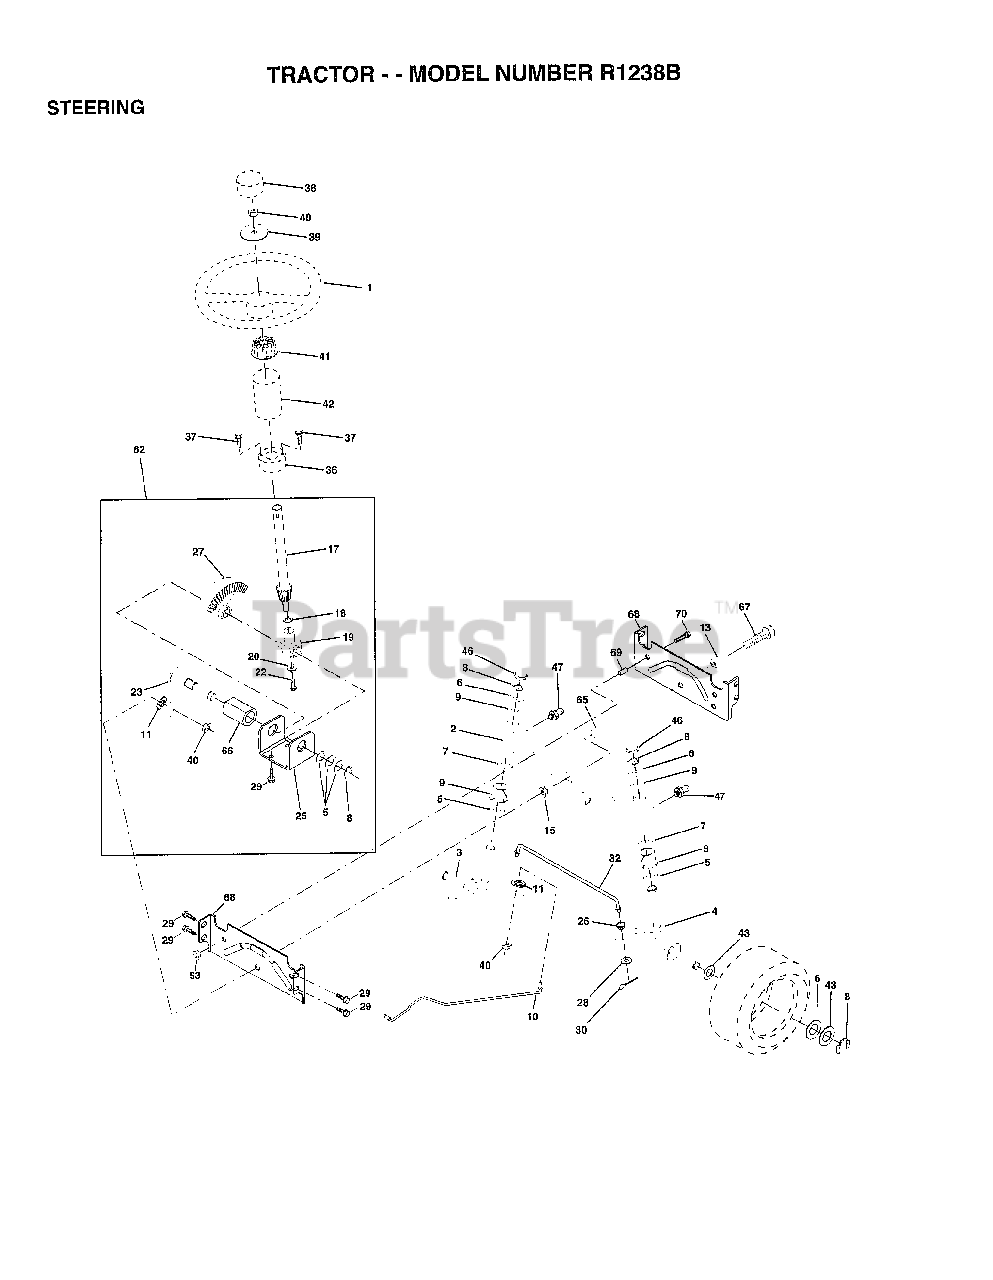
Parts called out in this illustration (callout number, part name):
2	AXLE ASM
3	SPINDLE.ASM.LH
4	"SPINDLE ASM,RH"
5	WASHER .T
6	WASHER
7	WASHER
8	RING
9	COL. SRTG. BEAR.
10	DRAGLINK-STAMPED
11	LOCKWASHER
13	BEARING AXLE
15	"NUT-LOC,FLANGE LT"
17	SHAFT ASSM STEERN
18	THRUST WASHER
19	SUPPORT.SHAFT
22	SCREW HEX SOC1/4-
25	BRKT-STEERING
26	BUSHING.DRAGLINK
27	GEAR SECTOR
28	WASHER
29	SCREW
30	COTTER PIN
32	TIE ROD
36	BUSHING.STEERING
37	"SCREW-TT,10-32 FL"
38	ST WHL INSERT CAP
39	WASHER T
40	GRIPCO NUT
41	ADAPTER-WHEEL LT
42	"TUBE, STR SHAFT"
46	CAP
47	ZERK M
62	STEERING ASM KIT
65	SPACER AXLE
66	"BEARING-ARM,PITMA"
67	BOLT
68	BRACE AXLE
